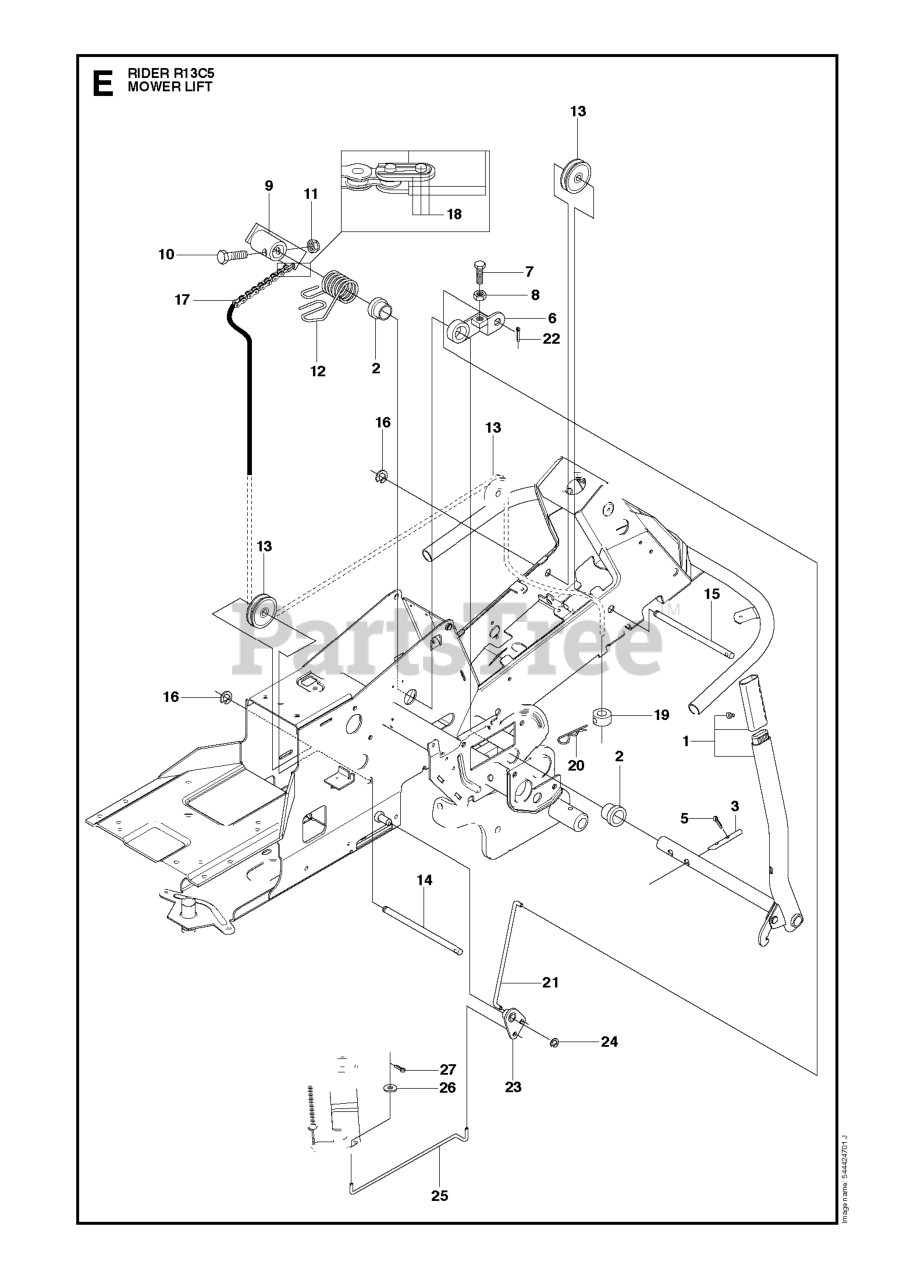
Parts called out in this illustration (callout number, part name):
1	LIFTING LEVER ASSY
2	BEARING FLANGE
6	LEVER CLUTCH
8	NUT
9	LIFTING ARM
21	CONNECTION ROD
24	RETAINING RING
25	CONNECTION ROD
